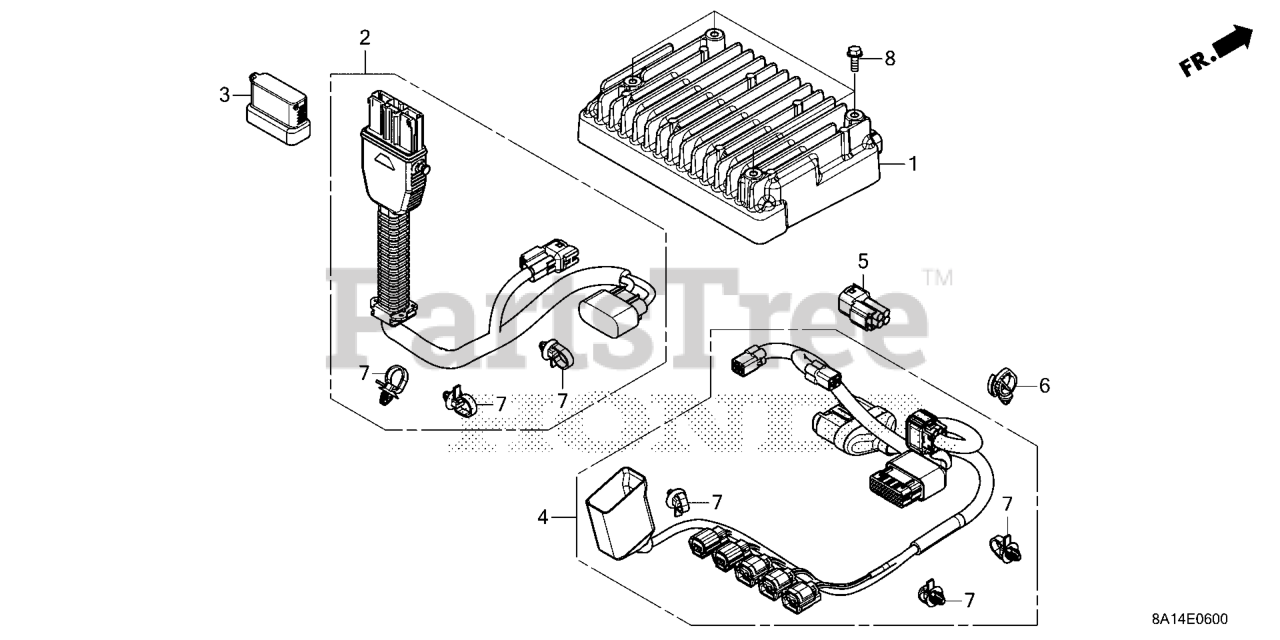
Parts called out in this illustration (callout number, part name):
2	CABLE ASSY., POWER
4	WIRE HARNESS, MAIN
5	CONNECTOR, DUMMY (4P)
6	CLIP, HARNESS
7	CLIP, HARNESS BAND (145MM) (BLACK)
8	BOLT, FLANGE (6X16)
